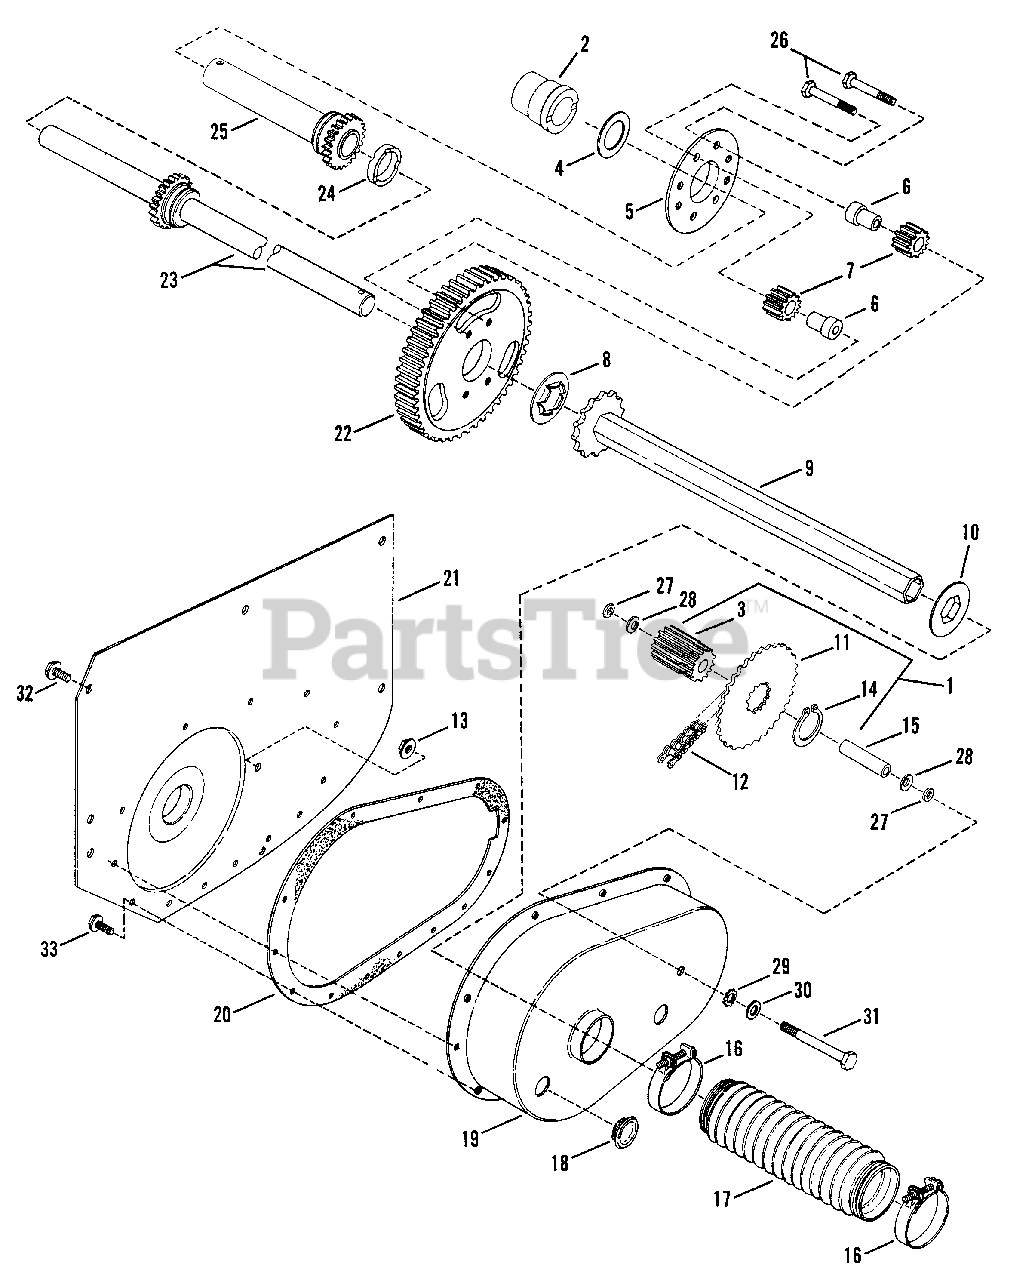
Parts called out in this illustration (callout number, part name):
1	ASSEMBLY, Gear/Sprocket
2	BEARING, Axle (Right Hand Fender)
3	GEAR 11 Teeth
4	WASHER, Thrust
5	PLATE, Differential
6	SPACER, Pinion
7	GEARS, Differential Pinion
8	WASHER, Thrust
9	ASSEMBLY, Drive Hex Tube
10	WASHER, Hex Nylon Splash
11	SPROCKET
12	CHAIN, 46 Pitch (#35)
13	NUT, 5/16-24 Hex Flange Lock
14	RING, External Retaining
15	SPACER
16	CLAMP, Boot
17	BOOT, Oil Seal
18	PLUG, Oil Fill & Check
19	CASE, Transmission
20	GASKET, Transmission Case
21	FENDER, Right Hand
22	GEAR, 63 Teeth-10 Pitch
23	AXLE, Long
24	SPACER, Differential (1.25" ID x .425 Wide)
25	AXLE, Short
26	SCREW, 5/16-24 x1-5/8" Hex Cap Special Lock
27	O-RING, 5/16"
28	WASHER, 5/16" Belleville
29	WASHER, 5/16" External Tooth Lock
30	WASHER, 5/16" Flat
31	BOLT, 5/16-24 x 2-5/8" Idler
32	SCREW, 5/16-1 8 x 5/8" Self-Tapping
33	SCREW, 1/4-20 x 5/8" Self-Tapping
